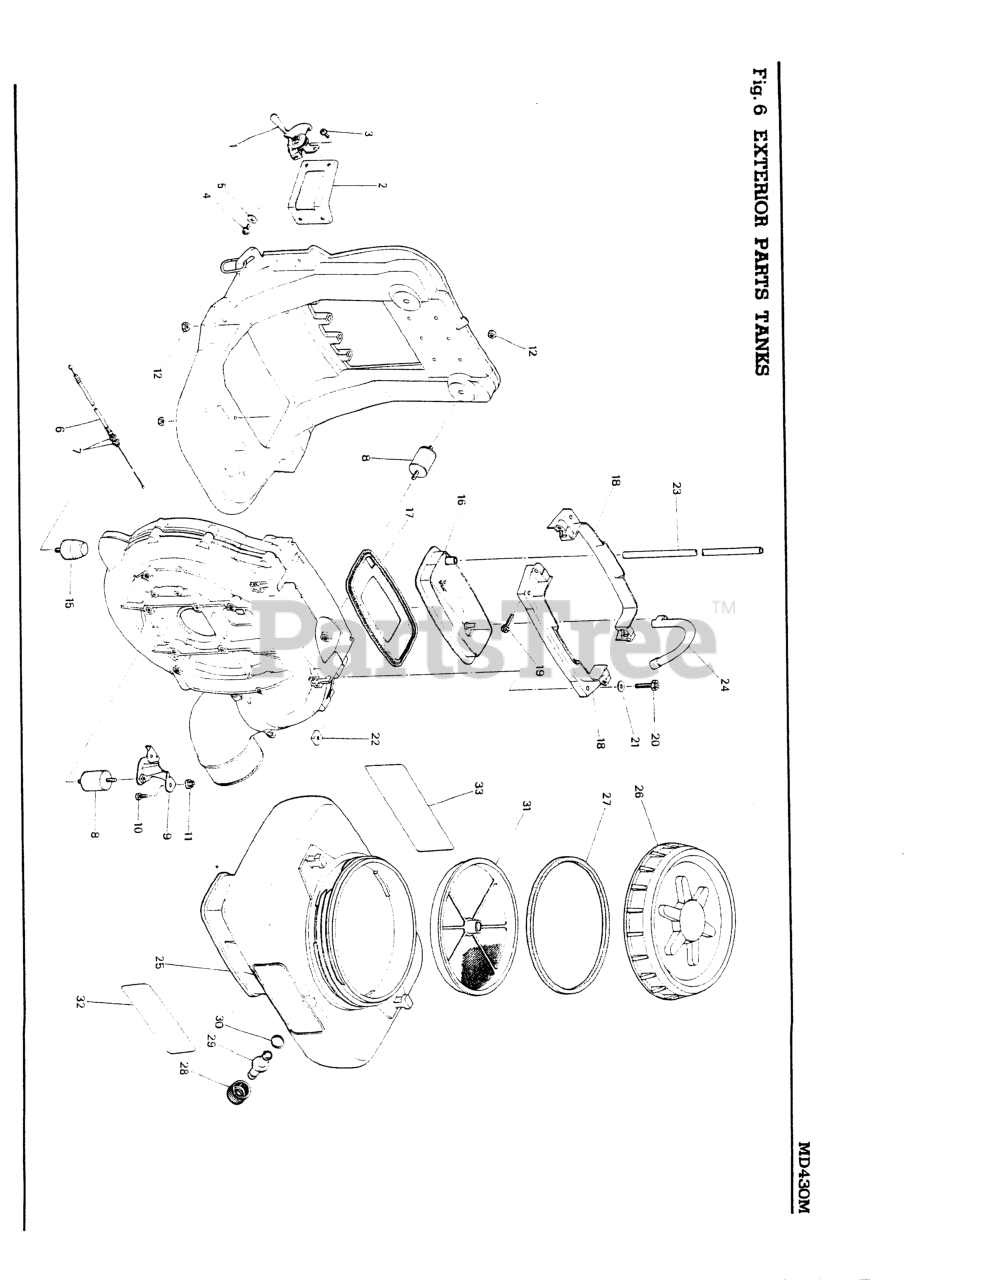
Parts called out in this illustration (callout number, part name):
3	SCREW, M5 x 12
4	SCREW, M5 X 12
5	WASHER (USE 181741)
7	NUT, M6 X 5
10	SCREW, M5 x 16
11	WASHER
12	NUT, M6 X 5
16	COVER ASSEMBLY
19	BOLT, M6 x 25
20	BOLT, M6 x 40
21	WASHER, M6 x .8
22	NUT
26	CAP ASSY
